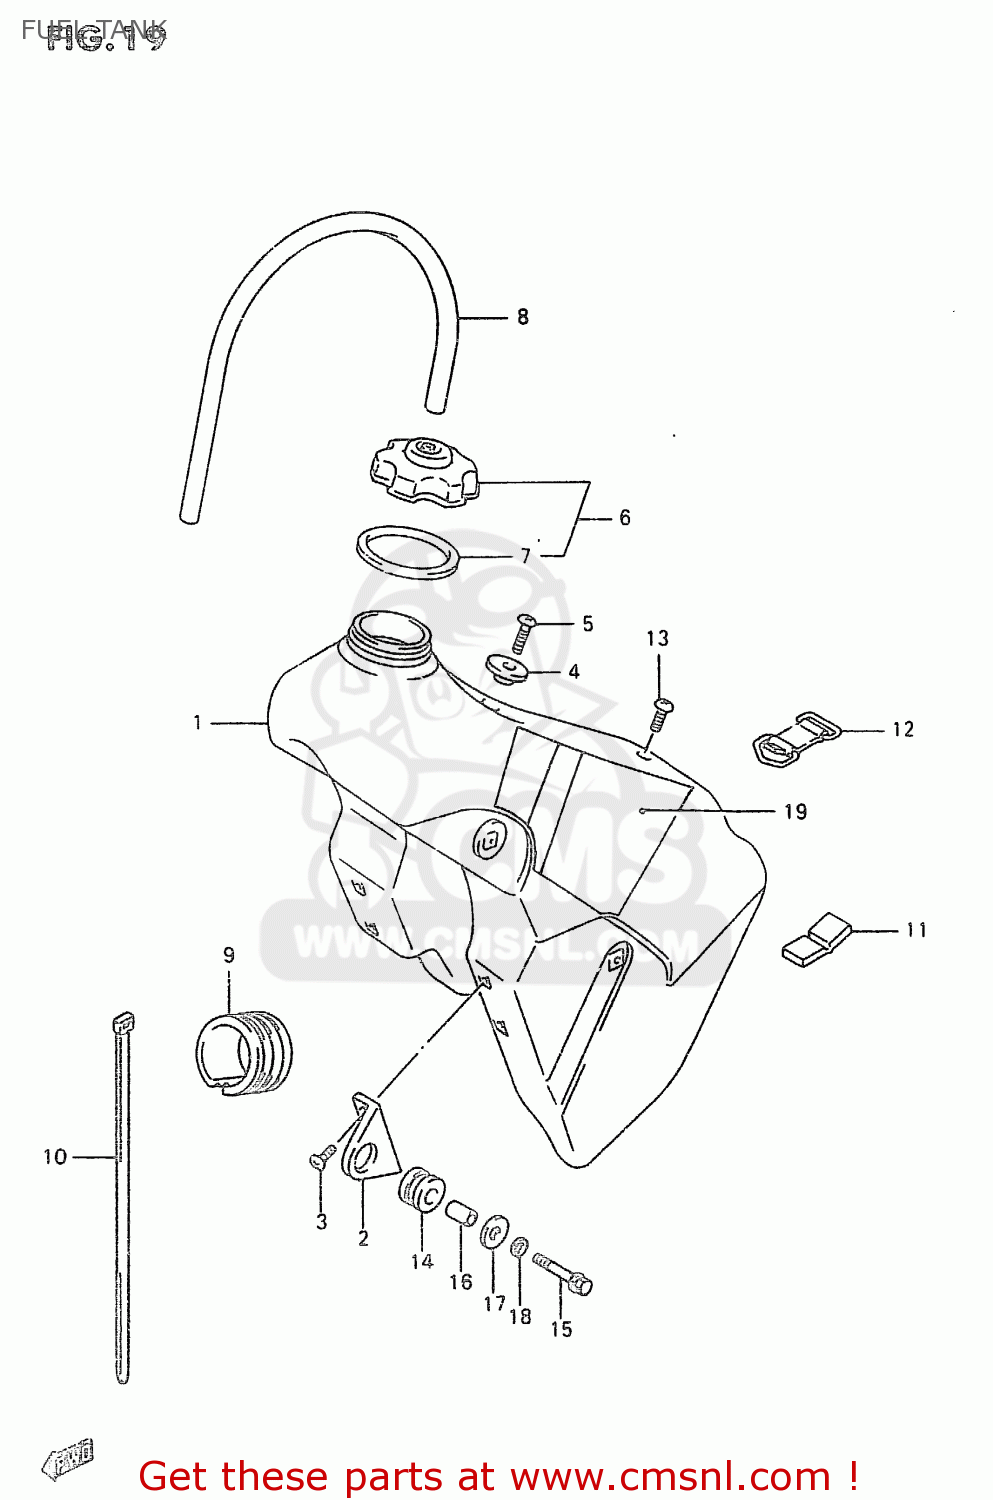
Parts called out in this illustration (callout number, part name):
1	TANK COMP,FUEL
2	BRACKET,FUEL TANK FR
3	SCREW
4	HOOK,SEAT FR
5	SCREW
6	CAP SET,FUEL TANK
7	GASKET,CAP (NAS)
8	HOSE (5.3X10.5X600)
9	CUSHION,FUEL TANK NO.1
10	CLAMP(L:300)
11	CUSHION
12	BAND,FUEL TANK RR
13	SCREW
14	CUSHION,MUFFLER
15	BOLT,G/S SWITC
16	SPACER(6.5X9X13.5)
17	WASHER(6.5X24X1.2)
18	LOCK WASHER
19	TAPE SET,FUEL TANK
